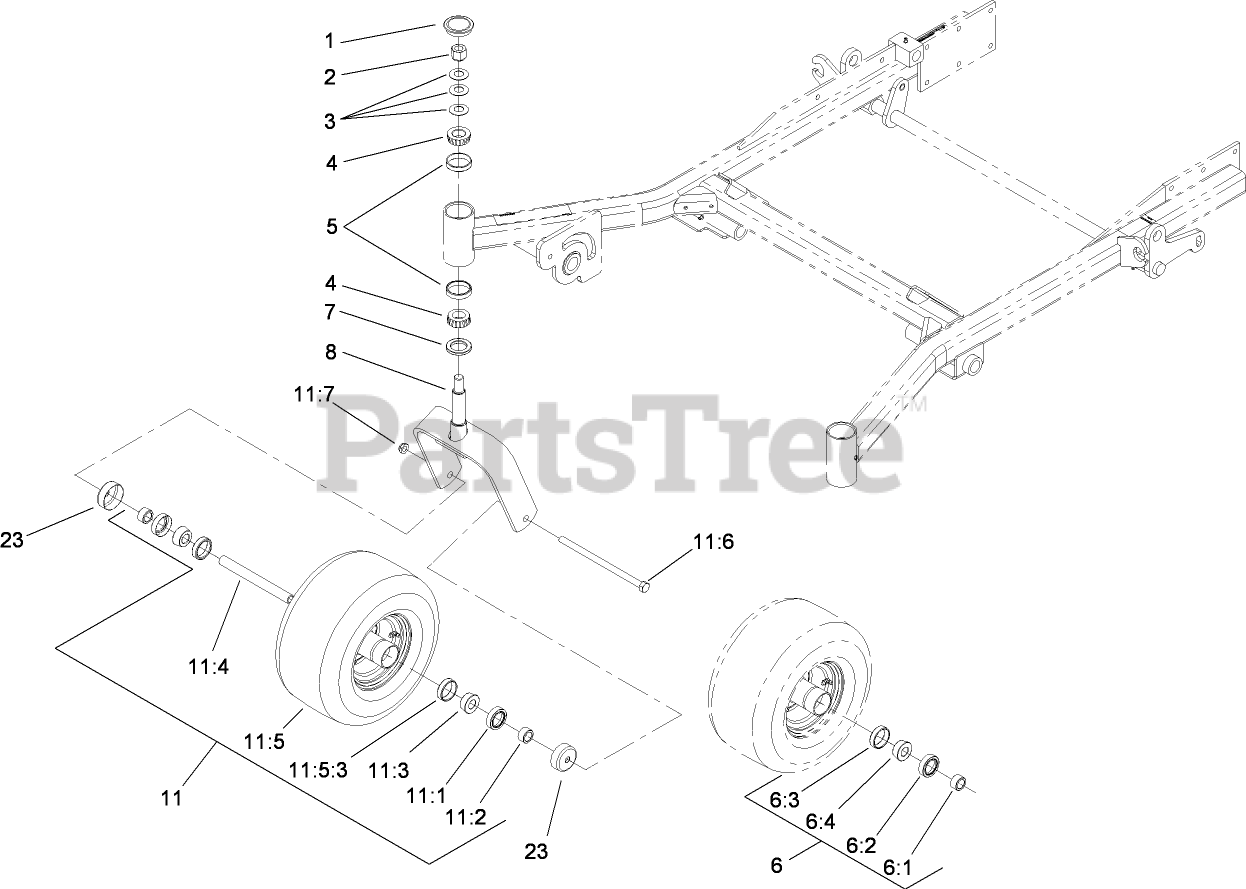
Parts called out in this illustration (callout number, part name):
1	CAP-GREASE
2	NUT-LOCK, NI
3	WASHER-BELLVILLE
4	BEARING-CONE, TAPERED
5	BEARING-CUP, TAPERED
6	CASTER WHEEL BEARING KIT
6:1	SPACER-BEARING
6:2	SEAL-BEARING
6:3	BEARING-CUP
6:4	BEARING-CONE, TAPER
7	SEAL-GREASE
8	CASTER
11	CASTOR WHEEL ASM
11:1	SEAL-BEARING
11:2	SPACER-BEARING
11:3	BEARING-CONE, TAPER
11:4	SPACER-CASTER, FRONT
11:5	WHEEL AND TIRE ASM (SEMI-PNEUMATIC)
11:5:3	BEARING-CUP
11:6	SCREW-HH
11:7	NUT-LOCK, NI
23	GUARD-SEAL
